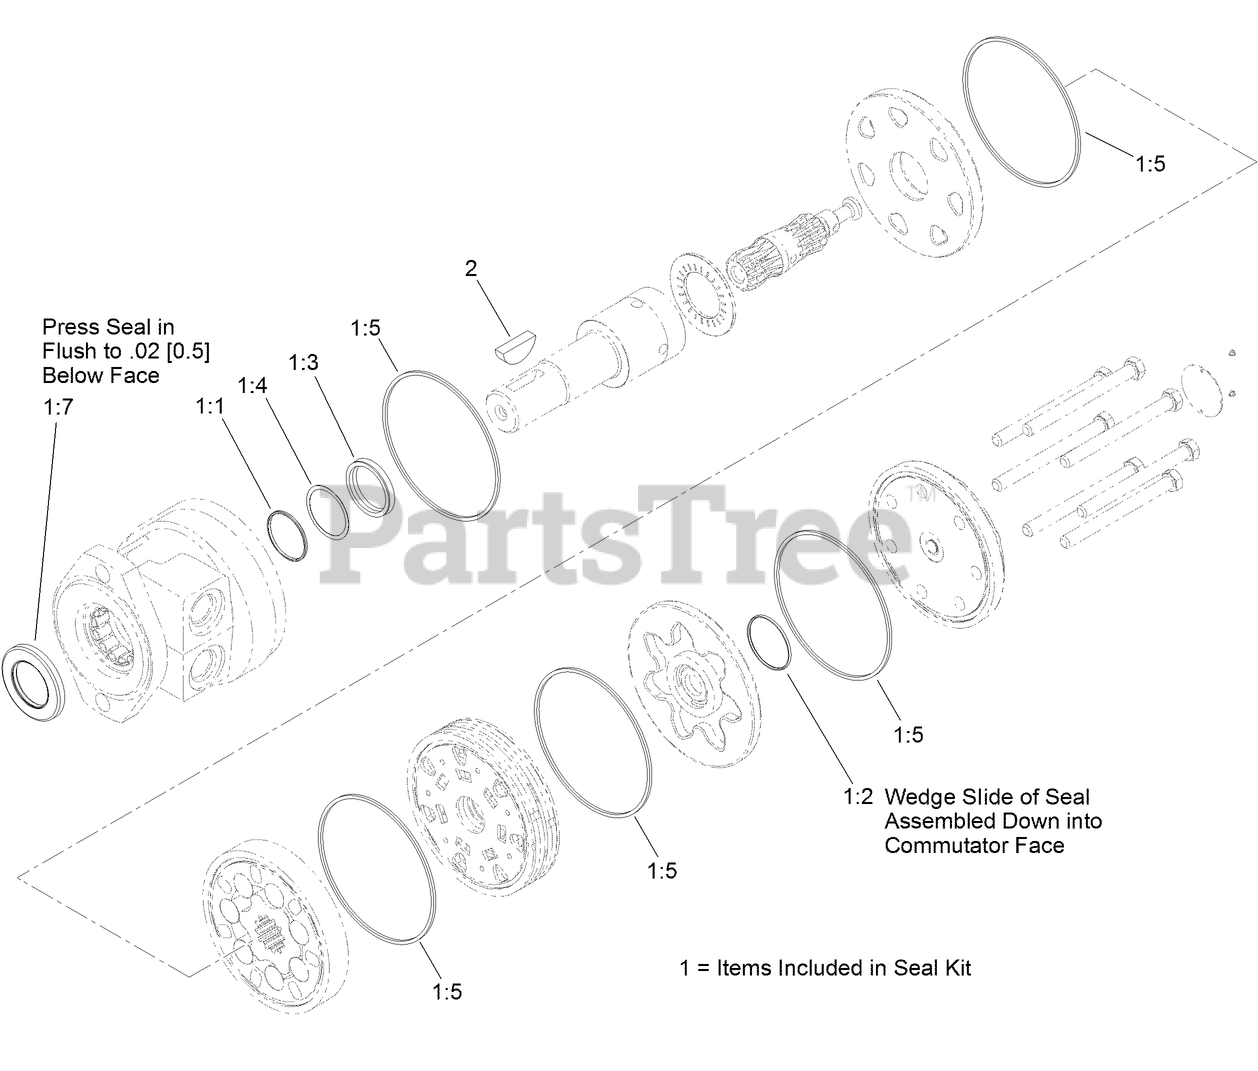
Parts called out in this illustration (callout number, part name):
1	SEAL KIT
1:1	Ring-Back Up
1:2	Seal-Commutator
1:3	SEAL-SHAFT (VITON)
1:4	WASHER-BACK UP (STEEL)
1:5	RING-SEAL (VITON)
1:7	Seal-Dirt and Water
2	KEY-SQUARE
